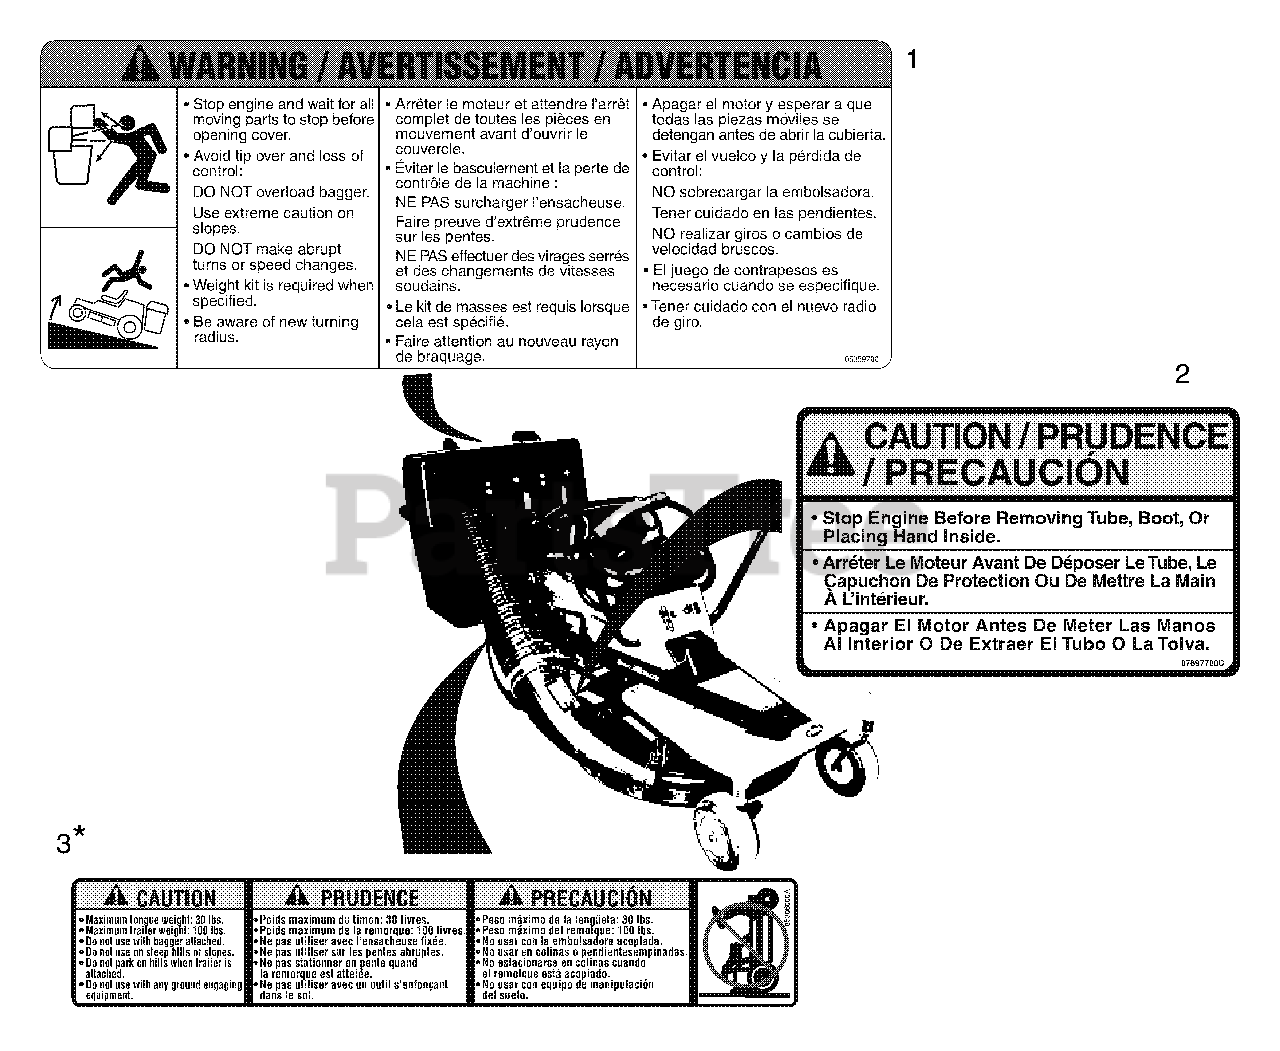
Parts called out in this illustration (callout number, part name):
1	Decal, Bagger Cover Warning
2	Decal, Boot Caution
3	Decal-Hitch 100#
